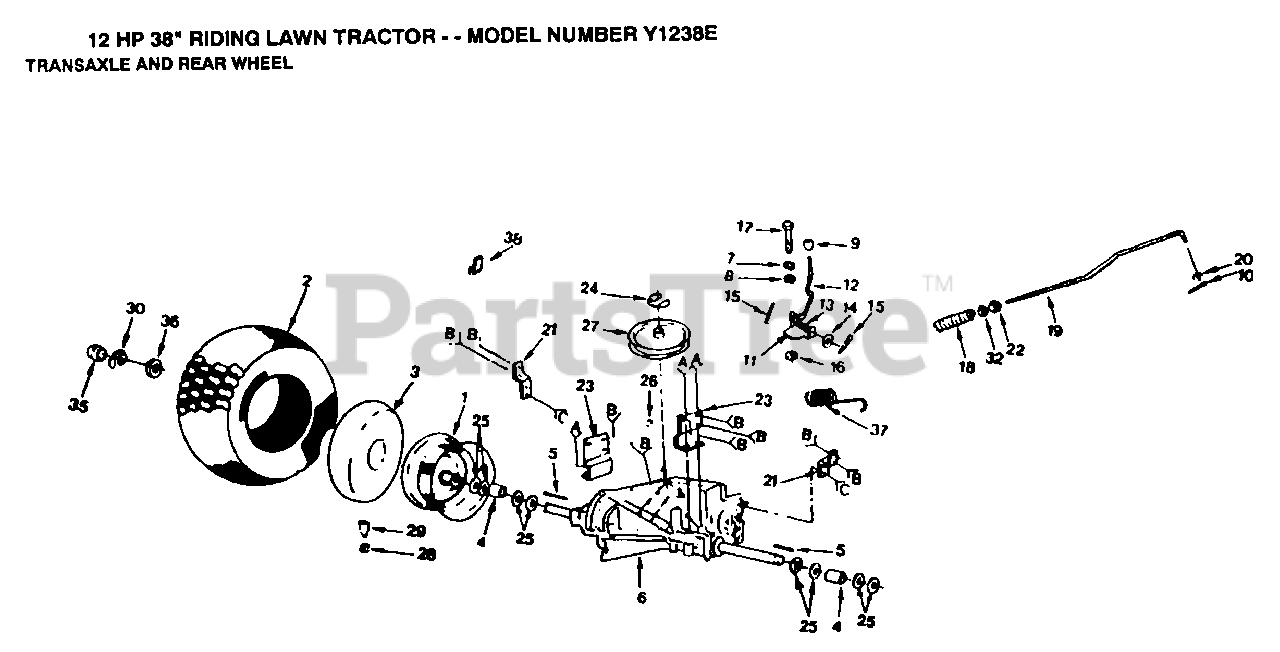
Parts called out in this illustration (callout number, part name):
3	TUBE.18X9.5-8
4	SPACER LT
5	SQUARE KEY
7	LOCKWASHER
8	WASHER LT
9	KNOB.DUCKHEAD.1/2
10	COTTER PIN
11	PLATE SHIFT LT
12	ROD SHIFTER
13	SPRING LT
14	WASHER
15	PIN COTTER 1/8
16	"LINK, CLUTCH T"
18	SPRING ROD LT
19	BRAKE ROD LT
20	WASHER
21	STRAP TORQUE
22	NUT
23	BRACKET LT
25	WASHER
27	PULLEY TRANS
28	VALVE CAP
29	VALVE STEM LT
30	E-RING LT
35	HUB CAP
36	WASHER
38	CLIP T
